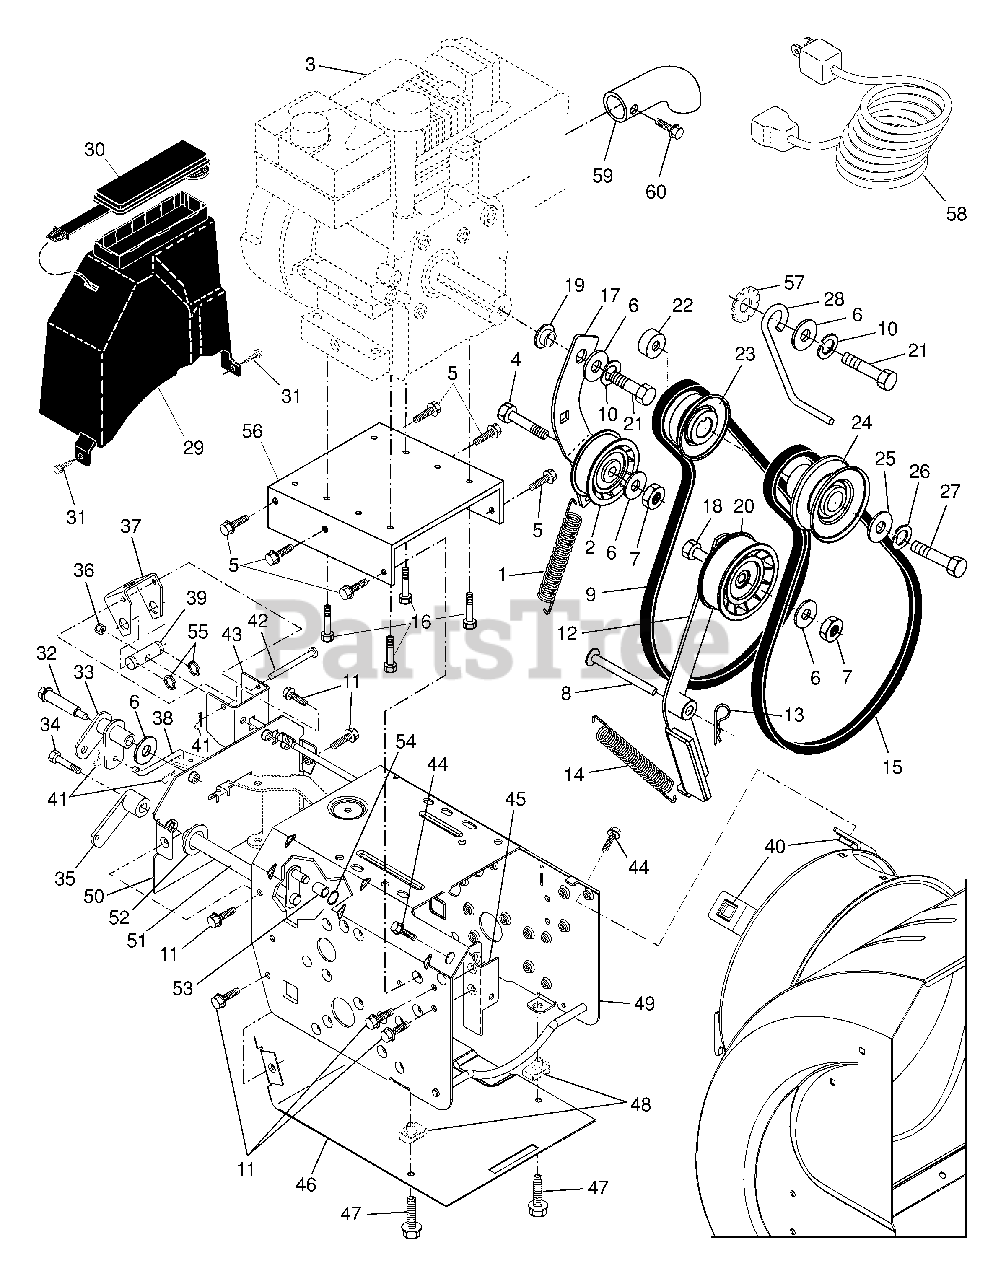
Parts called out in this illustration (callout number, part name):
1	Spring, Traction Idler
2	Pulley, Idler (2-1/4)
4	Screw, Hex Head 5/16-18 x 1-1/4
5	Screw, Hex Head 5/16-18 x 3/4
6	Washer, Flat
7	Nut, Jam, Lock 5/16-18
8	Pin, Idler Pivot
9	V-Belt, Traction Drive
10	Washer, Lock 5/16
11	Screw, Hex Washer Head 5/16-18 x 1/2
12	Idler Arm Assembly, Impeller
13	Retainer, Hairpin
14	Spring, Brake
15	V-Belt, Impeller Drive
16	Screw, Hex Head 3/8-16 x 1-1/4
17	Arm, Idler
18	Screw, Hex Head 5/16-18 x 1-1/2
19	Bushing, Idler Pivot
20	Pulley, Idler (2-3/4)
21	Screw, Hex Head 5/16-24 x 1
22	Spacer, Engine Pulley
23	Pulley, Engine, Traction Drive
24	Pulley, Engine, Impeller Drive
25	Washer, Flat 3/8
26	Washer, Lock 3/8
27	Screw, Hex Head 3/8-24 x 1-3/8
28	Guide, Belt
29	Belt Cover Assembly
30	Cover, Toolbox
31	Screw, Hex Head 1/4-20 x 1/2
32	Bolt, Shoulder 5/16-18
33	Bellcrank Shifter
34	Screw, Hex Head 1/4-28 x 3/4
35	Arm, Auger Control
36	Nut, Lock 5/16-18
38	Link, Speed Control
39	Trunnion, Clutch
40	Nut, Cage 3/8-16
41	Hairpin, Cotter 3/32 x 1/2
42	Pin, Bellcrank
43	Bracket, Bellcrank
44	Screw, Hex Head
45	Pivot Bracket, Impeller Idler Arm
46	Pan, Frame Bottom
47	Screw, Hex Head 5/16-18 x 3/4
48	Nut, Speed 5/16-18
49	Frame Assembly
50	Plate, Frame End
51	Shaft, Auger Control
52	Washer, Hardened
54	Ring, Crescent
56	Plate, Enging Mounting
57	Washer, Lock, External Tooth 5/16
58	Power Cord
59	Deflector, Muffler
